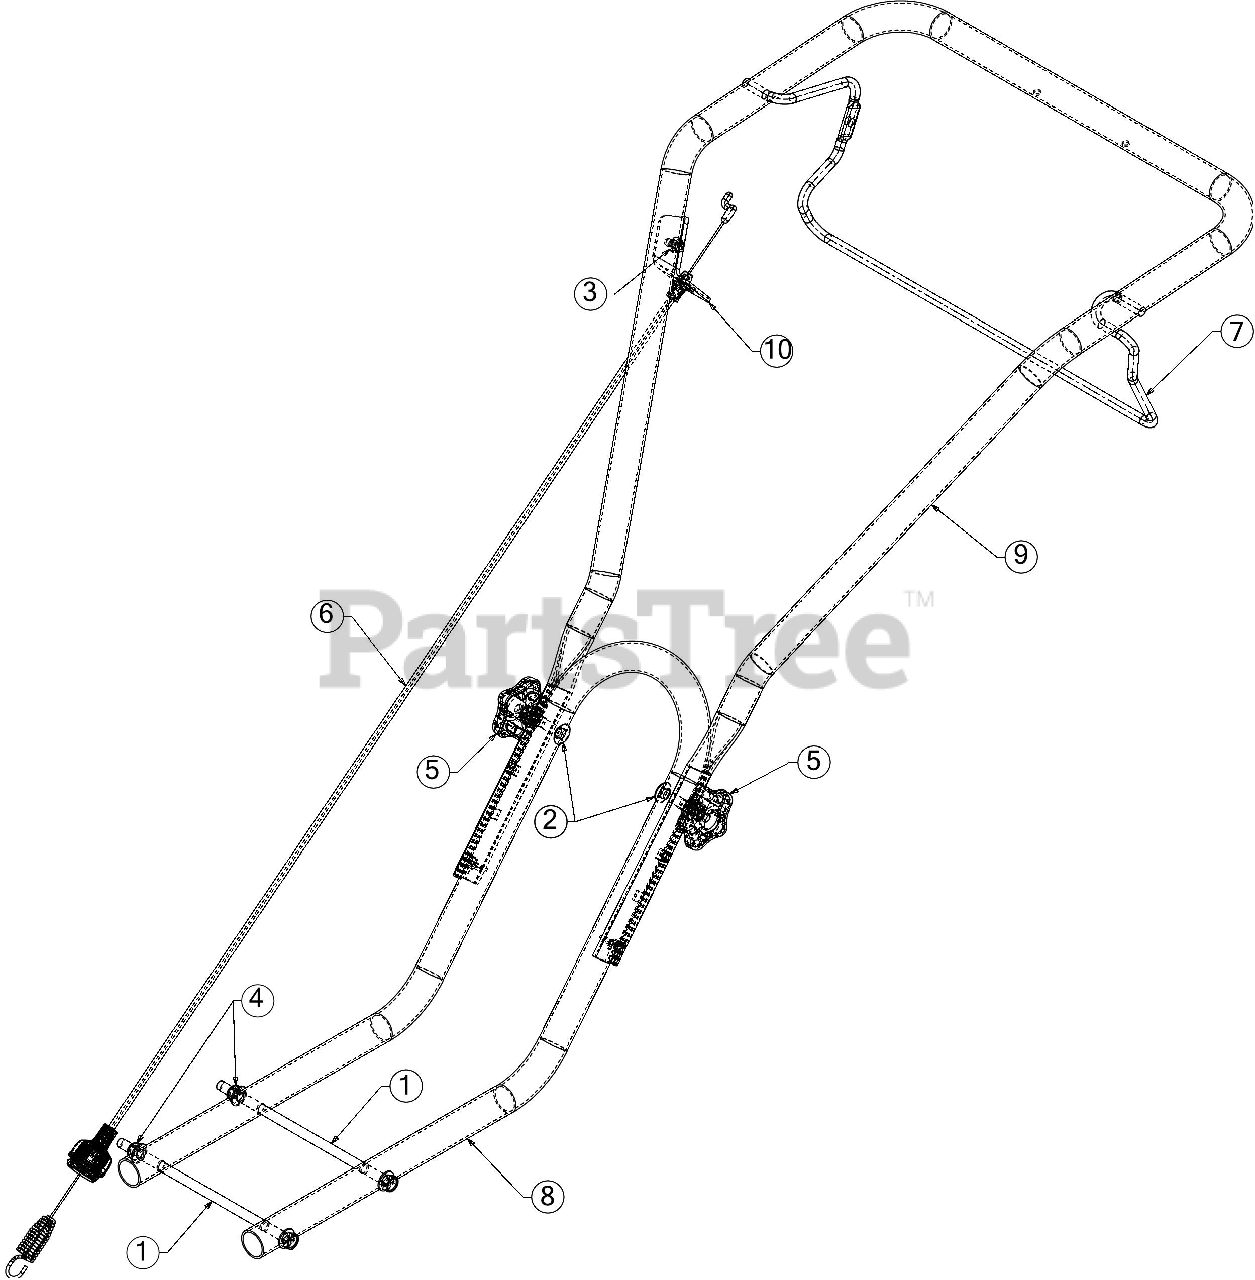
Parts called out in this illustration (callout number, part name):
1	SCREW 5/16-18 X 7.5 GR5
2	BOLT 5/16-18 X 2.00 GR5
3	SCREW 1/4-20 X.500
4	FLANGE LOCK NUT 5/16-18
5	STAR KNOB 5/16-18
6	CLUTCH FORWARD CABLE
7	CLUTCH BAIL
8	LOWER HANDLE
9	UPPER HANDLE
10	CABLE MOUNTING BRACKET
